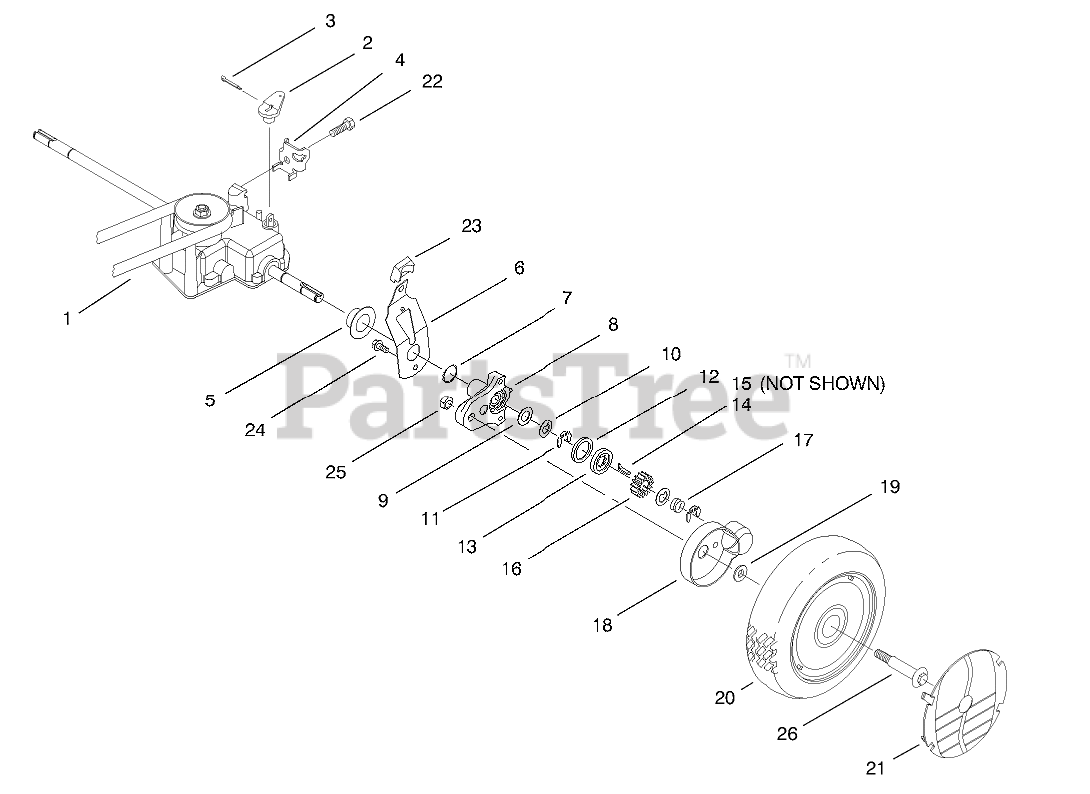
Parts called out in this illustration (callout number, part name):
1	V-BELT E
2	LEVER-SHIFT
3	PIN-COTTER
4	CLAMP-CABLE
5	CAP-END
6	SPRING ARM ASM
7	O-RING
8	ASM
9	WASHER-ARM, PIVOT
10	WASHER-THRUST, KEYED
11	RING-CLIP, LOCKING
12	RING-FRICTION
13	WASHER-CLUTCH
14	KEY-ROCKING, LH
15	KEY-ROCKING, RH
16	GEAR-PINION
17	SPRING-COMPRESSION
18	COVER-WHEEL
19	SPACER-COVER, WHEEL
20	WHEEL AND TIRE ASM (W/GEAR)
21	WHEEL COVER
22	SCREW-HWHTF
23	KNOB-ARM
24	SCREW-HWH
25	NUT-LOCK
26	BOLT-WHEEL
